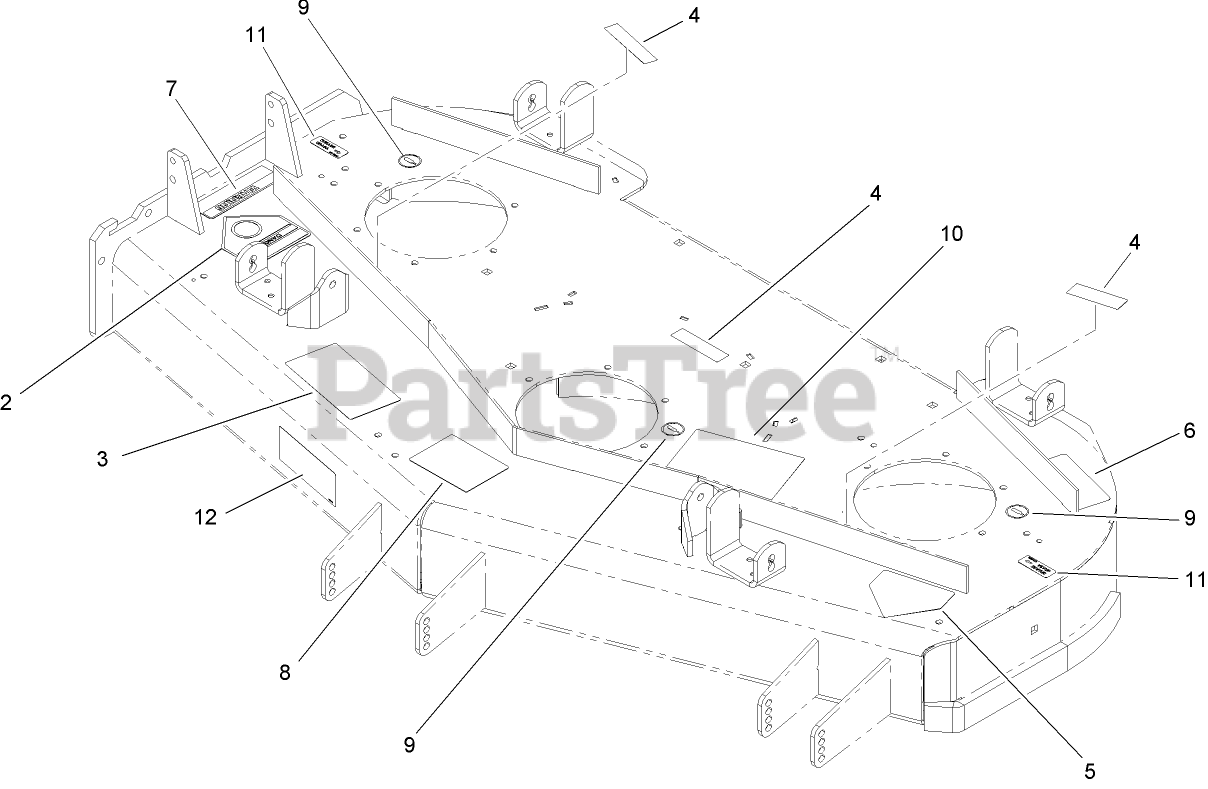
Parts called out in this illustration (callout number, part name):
2	DECAL-DANGER
3	DECAL-DANGER, THROWN OBJECT
4	DECAL-COVER, MISSING
5	DECAL-DANGER
6	DECAL-TORQUE
7	DECAL-WARNING
8	DECAL-SCALP, ANTI
9	DECAL-GREASE
10	DECAL-AID, SERVICE
11	Decal-Grease
